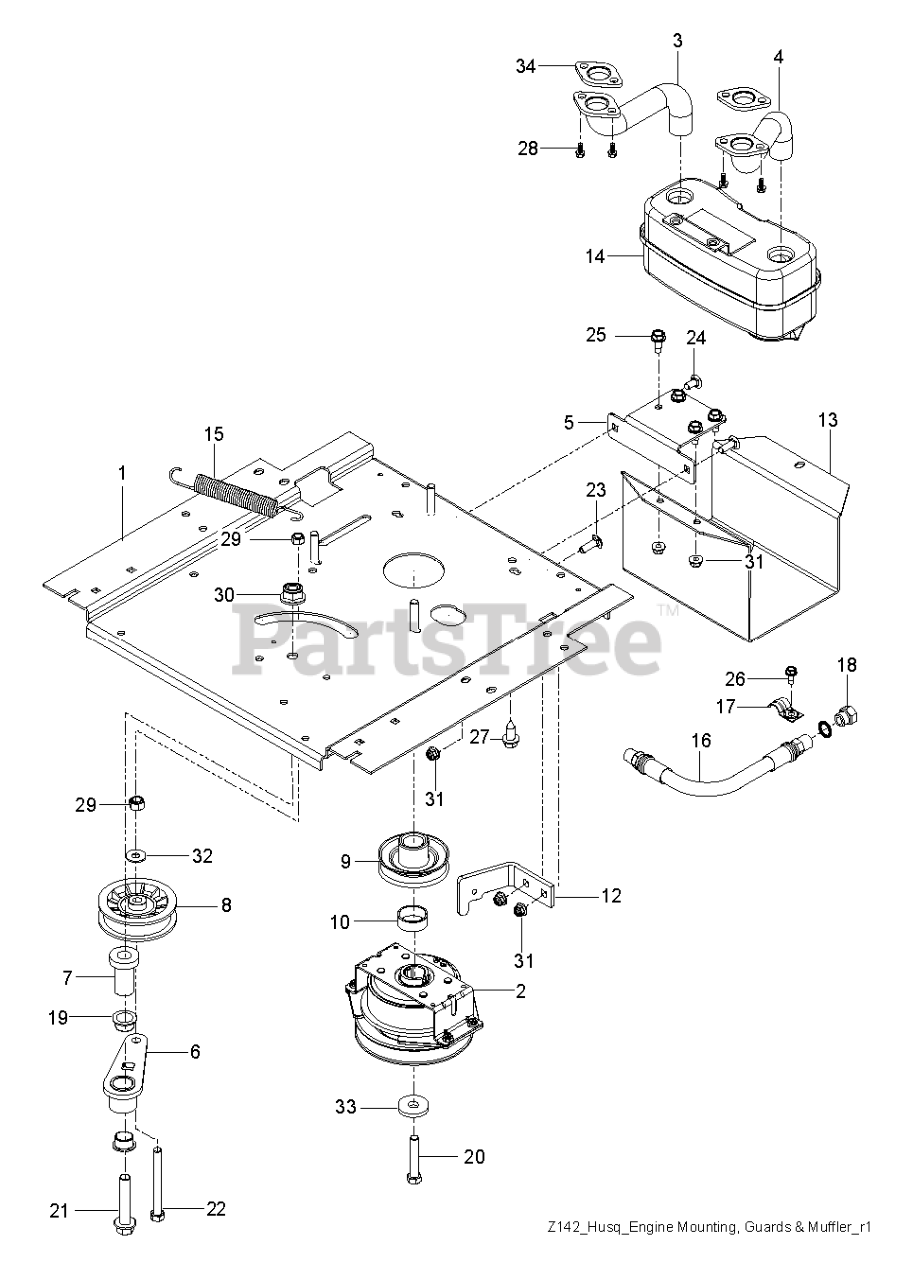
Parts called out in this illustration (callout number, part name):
1	PLATE ENGINE; RZ, 23IN BLACK
2	CLUTCH.105.FT-LBS
3	PIPE.EXHAUST.RH.CV18/20
4	PIPE.EXHAUST.LH.CV18/20
5	BRACKET MUFFLER MS431BLK
6	ARM IDLER
7	SPINDLE.IDLER
8	PULLEY, IDLER RAKE & ZTR
9	PULLEY.ENGINE
10	T & B SPACER
12	STOP, CLUTCH, BLACK
13	GUARD.MUFFLER.WO.TOW.HITCHX431
14	MUFFLER ASM TWIN
15	SPRING, DECK DRIVE
16	HOSE.ASSEMBLY.OIL.DRAIN
18	PLUG OIL DRAIN
19	BEARING.FLANGED.PLASTIC.3/4ID
20	CLUTCH BOLT7/16-20X3.5 GR524HR
21	BOLT.FLANGE.1/2-13 X 2.75.GRD5
22	HCS 3/8-16X3-1/2 TAPBLT GR5 ZD
23	RHSNB 5/16C X 1
24	BOLT 5/16C X 3/4" CARRIAGE
25	SCREW.THDROL.5/16-18X3/4.TTY
26	SCR 1/4-20X5/8 HEX SELF TAP ZD
27	SCREW 3/8-16X1
28	SCREW.SOCKET.HEAD.5/16-18
29	NUT 3/8-16 NYLOC
30	NUT, 1/2-13 HEX FLG NYLOC ZD
31	5/16-18 NYLOC FLANGE NUT
32	WASHER.5/16.FLAT.STE.STD.
34	GASKET.EXHAUST.KOHL.CV18-CV26
